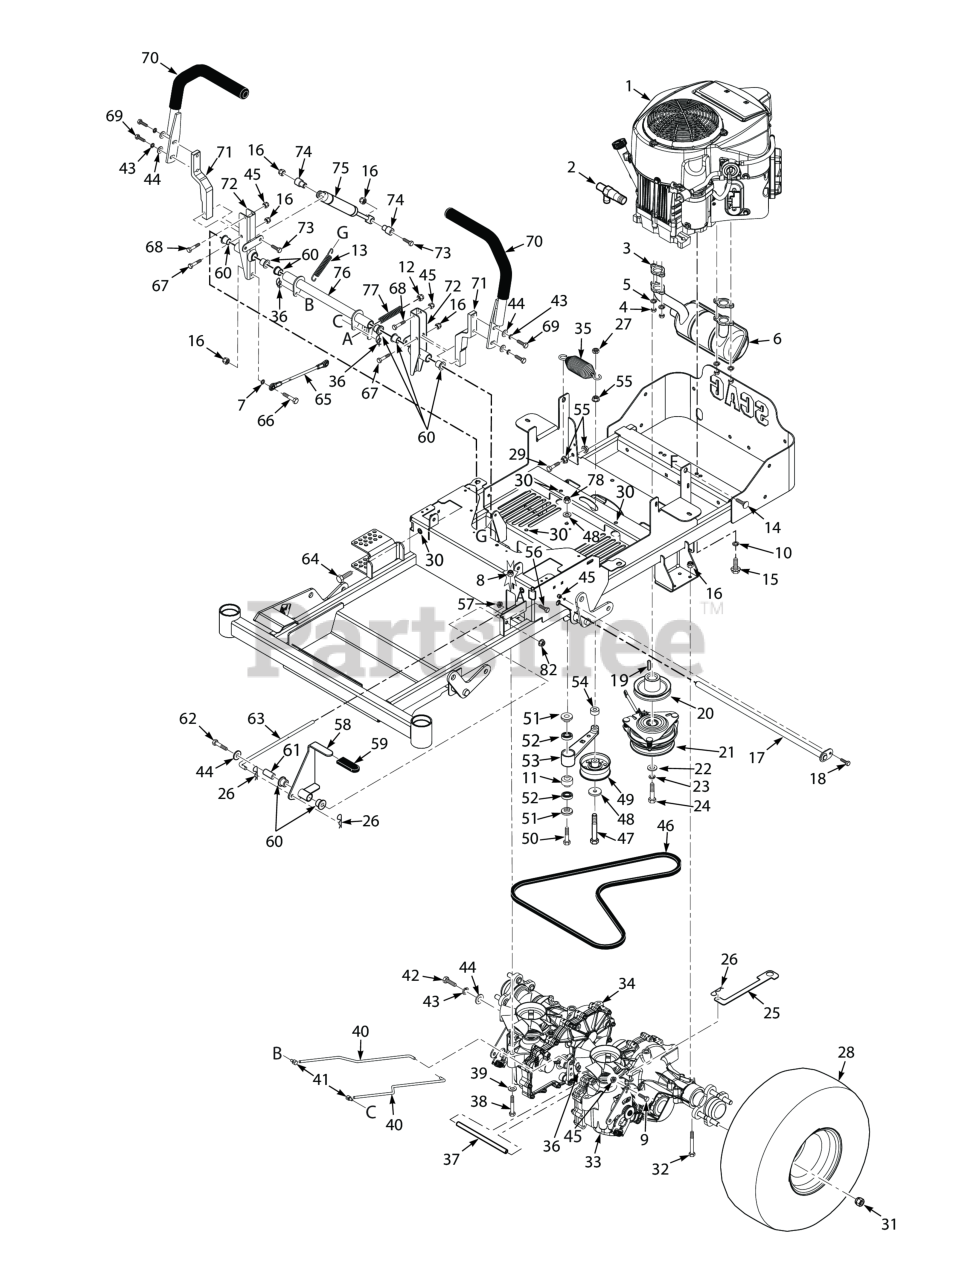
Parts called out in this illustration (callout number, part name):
1	Engine, Kawasaki - FR600V
2	Oil Drain, Kawasaki
3	Gasket, Exhaust
4	Nut, M8 x 1.25 Hex Special
5	Lockwasher, M8 Spring (Kawasaki)
6	Muffler, Kawasaki FR/FS600V
7	Lockwasher, 5/16 (.317 x .586 x .078) Helical Spring
8	Nut, Flange Head Elastic Stop 5/16-18
9	Bolt, Hex Head, 1/4-20 x 1-1/2"
10	Lockwasher, 3/8" Spring, Kawasaki FX / FS
11	Spacer, Bearing
12	Nut, Flange Elastic Stop Nut, 3/8-16
13	Spring, Deck Latch
14	Serr. Fl. Hex Head CPSCR, 1/4-20 x 3/4"
15	Bolt, Hex Head 3/8-16 x 1-1/4", Kawasaki FX / FS
16	HEX NUT, ELASTIC STOP LOCK, 5/16-18
17	Shaft Weldment, Control Arm
18	BOLT, HEX HEAD, 1/4-20 X 5/8
19	Key, 1/4 x 1/4 x 1.25" Pulley Mtg.
20	Pulley, 4-1/2" - 1" Bore
21	Electric Clutch Assembly
22	Flatwasher, 7/16-.469 x 1.75 x .25 (48, 52)
23	Lockwasher, 7/16� Spring
24	Bolt, Hex Head 7/16-20 x 3¼" w/Patch
25	Lever, Dump Valve
26	HAIR PIN, .08 DIAMETER X 1-3/16"
27	Bolt, Hex Head 3/8-16 x 1" Ser. Flg.
28	Wheel Assembly, 20 x 8.0-10
29	Bolt, Hex Head 3/8-16 x 1-1/2" Grade 8 Black
30	Threaded insert, Hex Head (Pressed)
31	Wheel Nut, 1/2-20 x 13/16
32	Bolt, Hex Head, 5/16-18 x 2.75 Zinc.
33	Transaxle, LH- ZT-2800
34	Transaxle, RH- ZT2800
35	Spring, Transmission Drive
36	Pin, Rue Cotter 3/8" Diameter
37	Spacer, Axle
38	BOLT, HEX HEAD, 5/16-18 X 2-1/4
39	Flatwasher, 5/16-.375 x .875 x .083 (35BV & 37BV-EFI)
40	Rod, Brake
41	Joint, Swivel
42	Bolt, Hex Head 3/8-16 x 2-1/4" - 61"
43	Lockwasher, 3/8" Spring, Kawasaki FX / FS
44	Flatwasher, 3/8" Special (.391 x .938 x .105)
45	HEX, NUT, ELASTIC STOP LOCK, 1/4-20
46	Belt, Transmission SZL-36
47	Capscrew, Hex Head 3/8-16 x 3-3/4"
48	Flatwasher, 3/8 (.391 x .938 x .105 HD) Grade 8
49	Pulley, 3-1/2" Dia.
50	Bolt, Hex Head 3/8-16 x 3" - 52"
51	Spacer, Controls
52	BEARINGS, BALL, NEUTRAL RETURN
53	Trans. Idler Arm Assy. (Includes 24, 79)
54	Spacer, Idler Pulley - SFZ61
55	NUT, 3/8-16 SERRATED FLANGE HEX HEAD
56	Bolt, Hex Head 5/16-18 x 1-1/2" (Right Front Engine Mounting, Briggs and Kohler Only)
57	Nut, Flange Elastic Stop Nut, 3/8-16
58	Brake Lever Assembly (INCL 59,60)
59	Grip, Brake Handle
60	Bearing
61	Pivot, Brake Lever
62	Capscrew, Hex Head 3/8-16 x 2-1/2"
63	Rod, Upper Brake Linkage
64	Bolt, Hex Head 3/8-16 x 3.0
65	Linkage Assembly, Steering
66	Bolt, 5/16 - 18 x 1 - 1/4" Hex Head
67	Bolt, Hex Head 5/16-18 x 1-1/2" - Front
68	Bolt, Hex Head, 1/4-20 x 1-1/4"
69	Bolt, Hex Head, 3/8-16 x 1 Gr. 5
70	Handlebar W/ Grip, SZL-36
71	Lever, Control Arm
72	Control Arm Weldment, SZL-36
73	Bolt, Hex Head 5/16-18 x 2-1/2" (x3) (35BV & 37BV-EFI)
74	Spacer, Pump Dampener
75	Damper, Steering
76	Bellcrank Assembly, Brake
77	Spring, Brake
78	HEX NUT, ELASTIC STOP LOCK, 3/8-16
